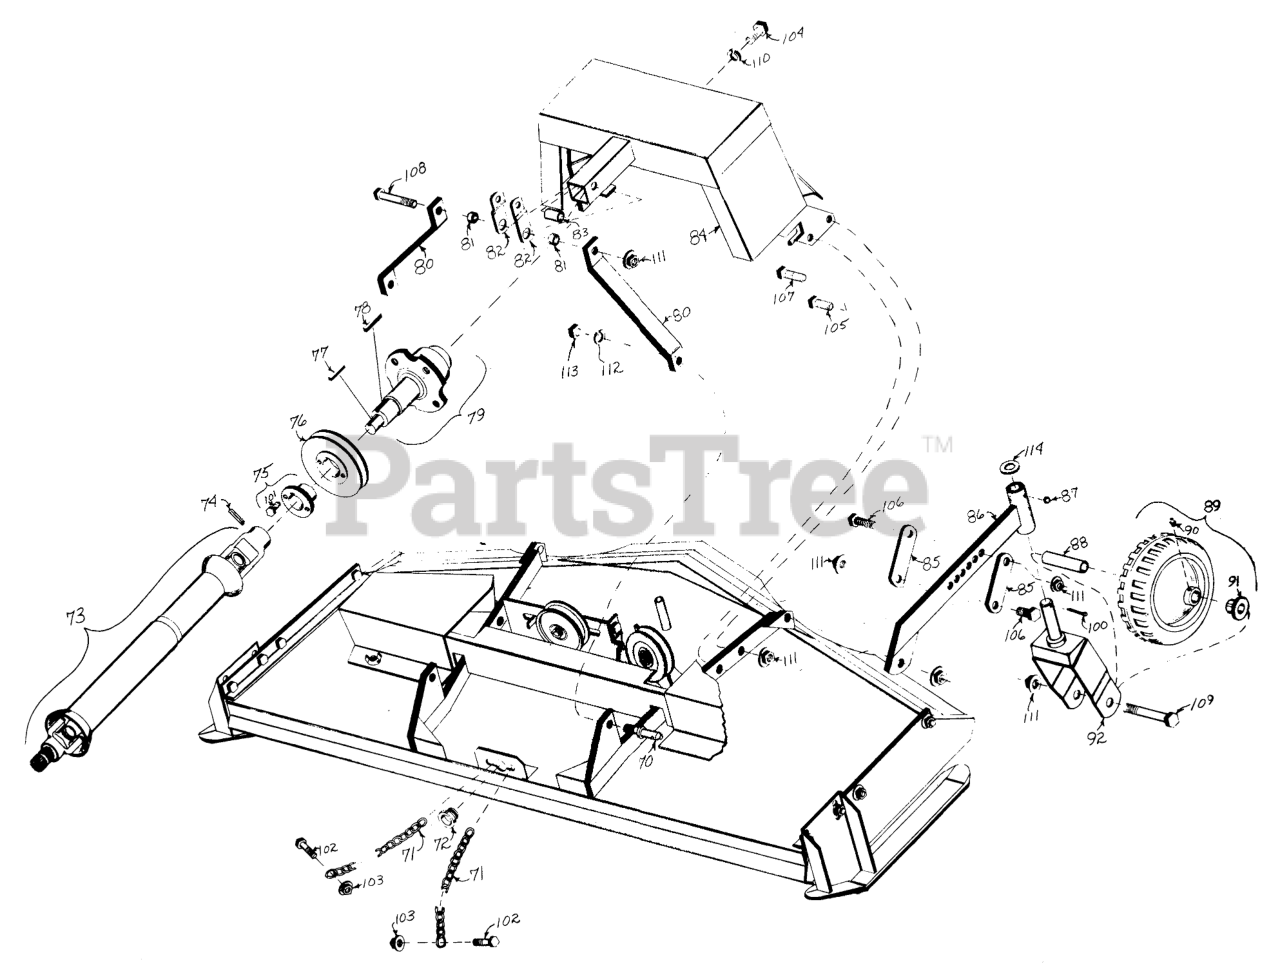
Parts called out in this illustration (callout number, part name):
70	Category "O" Mounting Pin
71	Check Chains
72	Plastic Caplug
74	Roll Pin 5/16 x 1 3/4
75	H 1 3/8 Straight Bore Bushing
76	5 PD Sheave
77	1/4 x 1/4 x 1/4 Key
80	A-Frame Bar
81	Strap
82	Top Pivot Link
83	17 GA wa x 5/8 x 1 1/4 Tube
84	Drive Spindle Support Assembly
85	Caster Arm Adjustment Bracket
86	Caster Arm
87	Grease Fining
88	U Bolt
89	Bearing
90	Clamp
91	FLANGE BEARING
91	Foot Rest
92	Caster Yoke
100	1/4 x 1 1/2 Cotter Pin
101	Bolt 1/4-20 X 3/4
102	Bolt, 3/8-16 x 1/2
103	Nut, Jam, 3/8-24 Thd
104	1/2 NF x 1 1/4 Hex Head Cap Screw
105	Bolt Hex 1/2-13 x 1 1/4
106	Bolt-1/2-13-1 3/4
107	Bolt-Hex 1/2-13 x 2
108	1/2 NC x 3 1/2 Hex Head Cap Screw
109	1/2 NC x 4 1/2 Hex Head Cap Screw
110	Lockwasher
111	1/2 NC Flange Lock Nut
112	5/8 Lock Washer
113	5/8 NC Hex Nut
114	Washer
